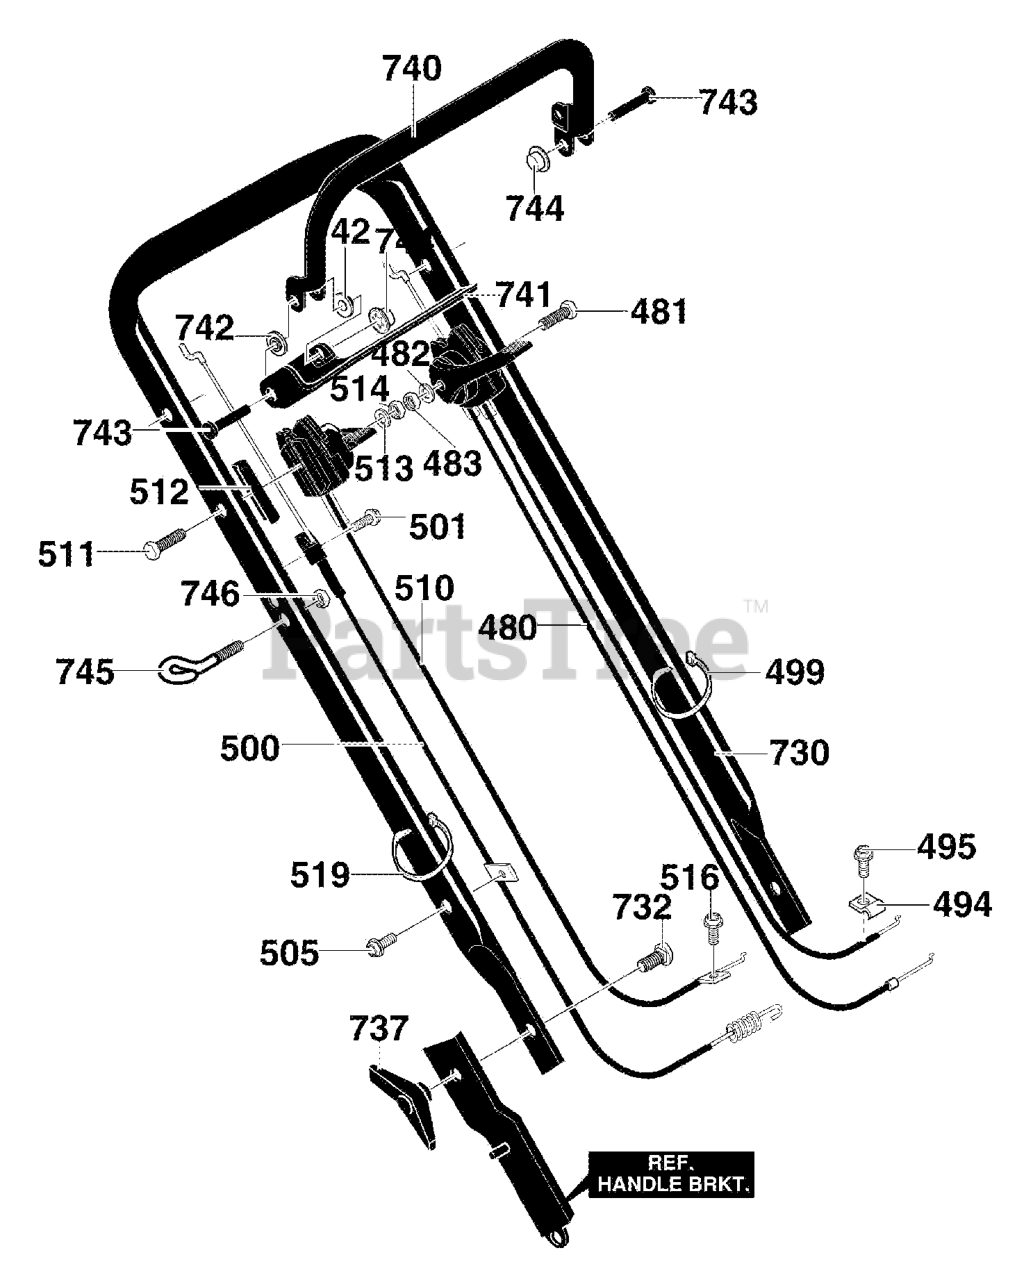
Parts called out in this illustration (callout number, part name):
480	CABLE, Throttle
481	SCREW, 1/4-20x2.50
482	FLATWASHER
483	NUT,1/4-20
494	Clamp, Throttle
495	SCREW, 10-32X.62
499	Cable Tie
500	Cable Drive Assy.
501	SCREW, #10-16X.50
505	SCREW, #10-16X.50
510	CABLE, Shifter Speed
511	SCREW, 1/4-20X3.00
512	SPACER, T-Control
513	FLATWASHER
514	NUT,1/4-20
516	SCREW, 10-32X.62
519	Cable Tie
732	BOLT, Carriage
737	KNOB, Wing
740	Stop Lever
741	LEVER, Drive Control
742	WASHER, Nylon
743	Clevis Pin
744	Cap, Push On
745	Rope Guide
746	NUT, 1/4-20
